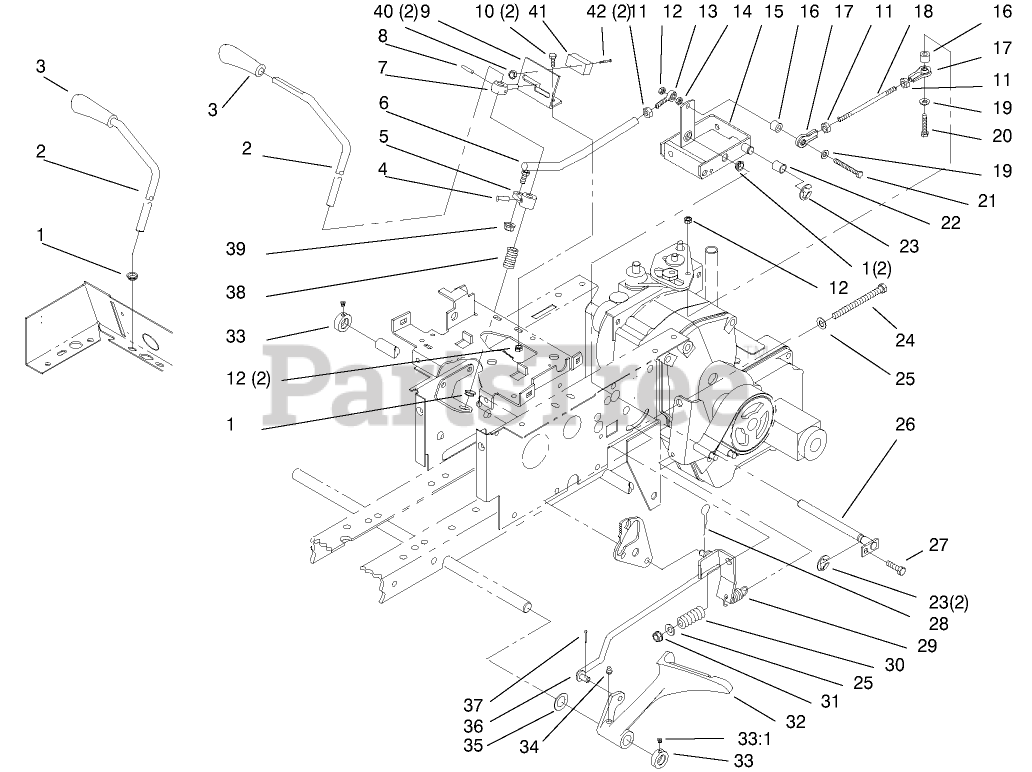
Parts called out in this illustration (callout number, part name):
1	BUSHING-NYLINER
2	ROD-MOTION CONTROL
4	SPIROL PIN 7/32X7/8
6	ASSY-ROD & BALL JOINT
7	GUIDE-CONTROL
10	SCREW-HH
11	NUT-JAM
12	NUT-LOCK, NI
13	ROD END, 1/4-28
14	NUT-HEX
16	BEARING CAM ROLLER
17	ASSY ROD END
18	ROD-CONTROL
19	WASHER-FLAT
20	SCREW-HH
21	HHCS 1/4X2.25 FULL T
22	BEARING-CAM RETURN
23	RING-RETAINING, EXTERNAL
24	SCREW-HH
25	WASHER-FLAT
28	PIN-HAIR
29	SPRING
30	SPRING-COMPRESSION
31	NUT-LOCK, NI
33	COLLAR
33:1	SCREW-HSH
34	FITTING-GREASE
35	WASHER
37	PIN-COTTER
38	SPRING-COMPRESSION
39	NUT-LOCK
40	NUT-HEX, NYL INS
41	SWITCH - CLUTCH
42	SCREW-PPH
